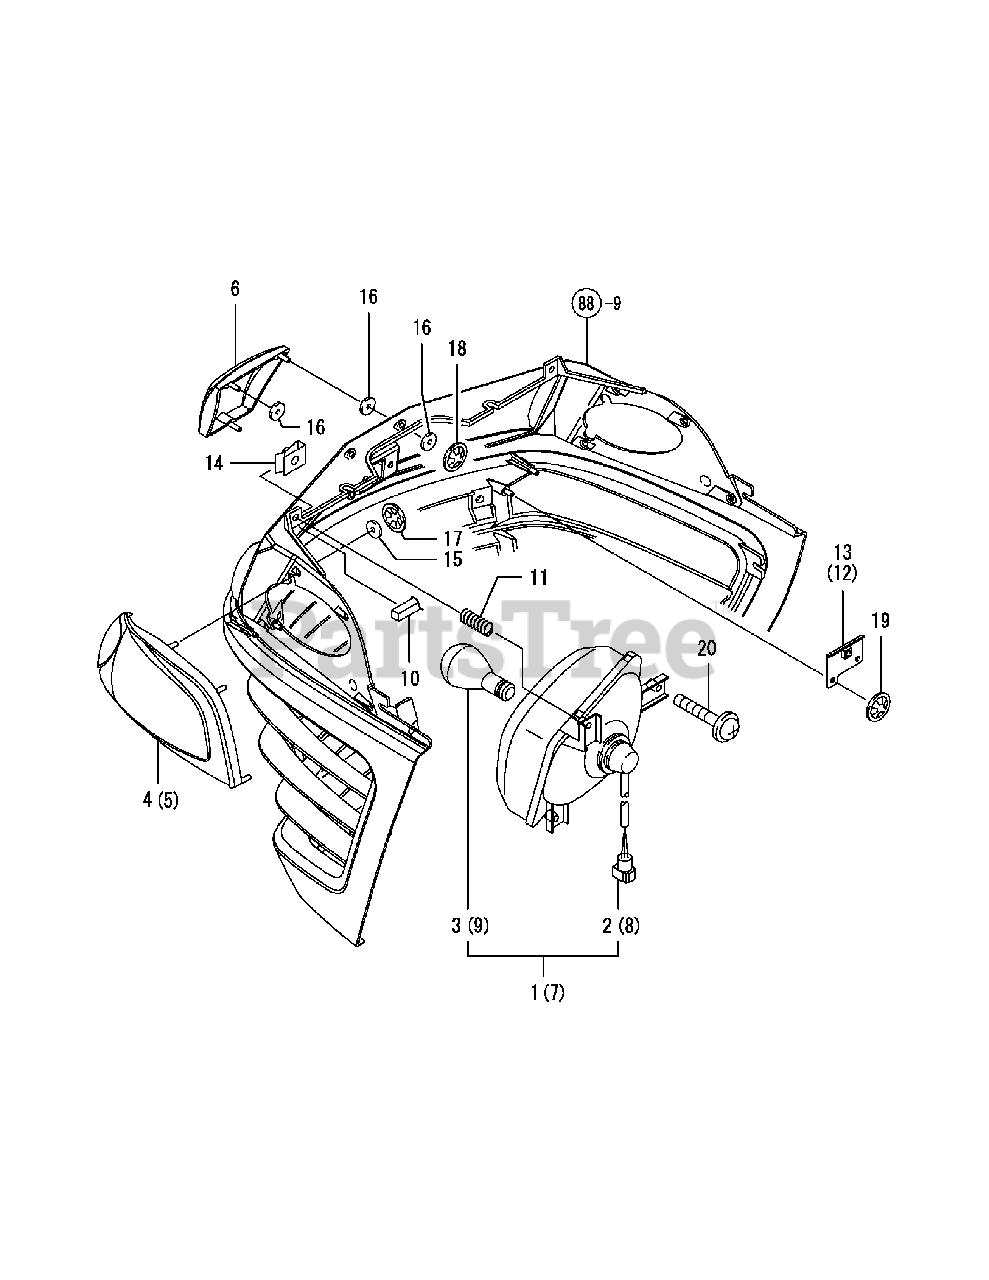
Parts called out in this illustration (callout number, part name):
1	HEADLIGHT ASSY, L.H.
2	WIRE ASSY, LEAD
3	BULB 12V45/45W
4	LENS, SIDE L.H.
5	LENS, SIDE R.H.
7	HEADLIGHT ASSY, R.H.
8	WIRE ASSY, LEAD
9	BULB 12V45/45W
10	SEAL, HEADLIGHT
12	BRACKET ASSY, L
13	BRACKET ASSY, R
17	NUT M5,SPEED
18	NUT M5,SPEED
19	NUT M5,SPEED
